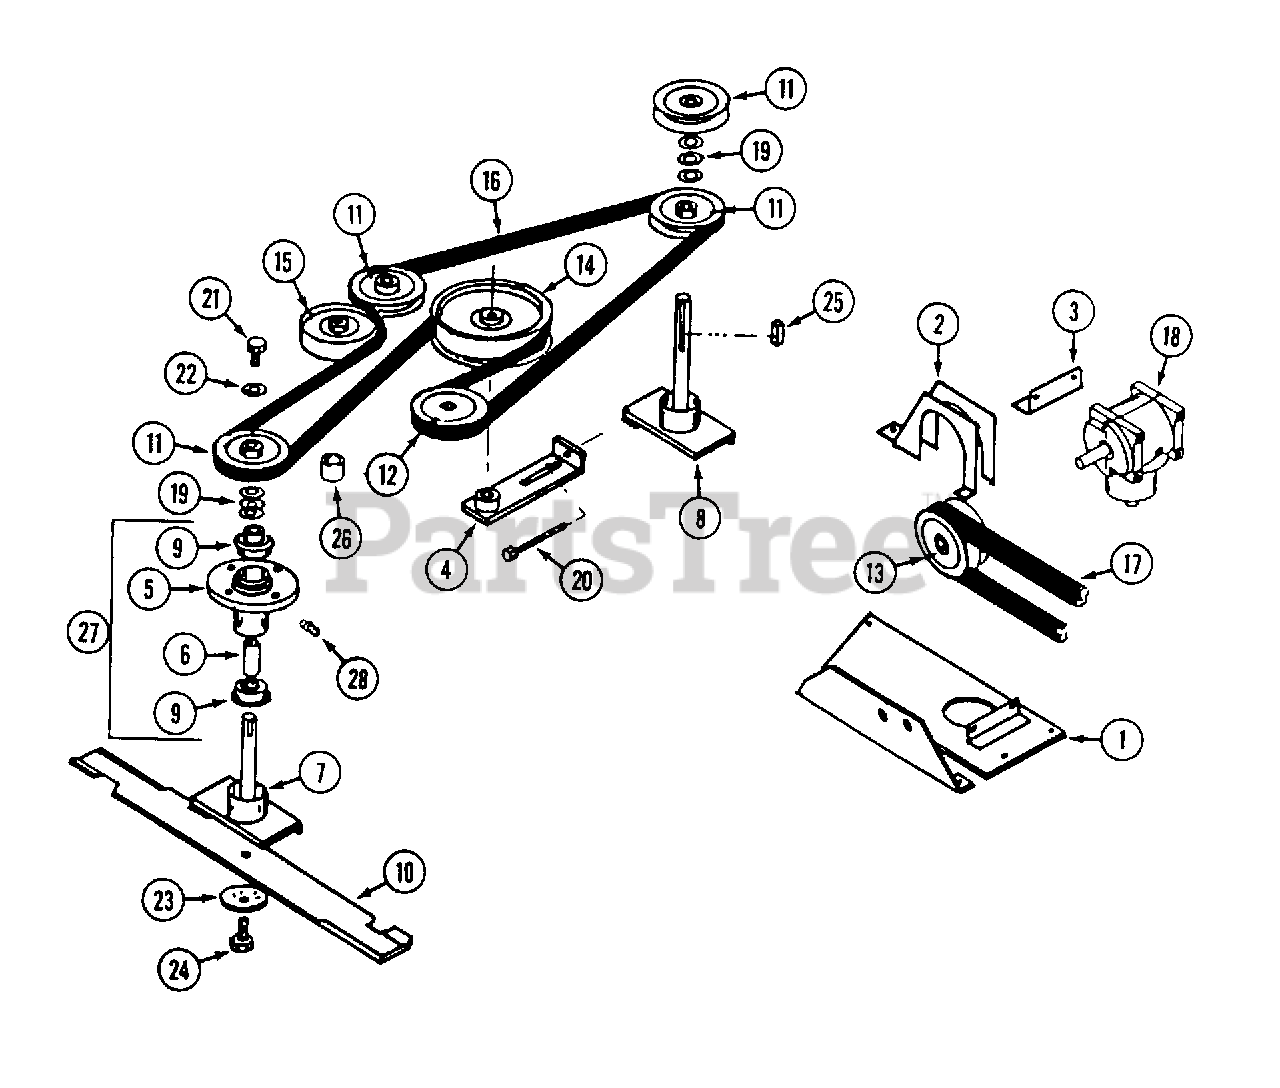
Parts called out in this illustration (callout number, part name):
1	MOUNT - gear box
3	ANGLE - gear box mount
4	TIGHTENER - belt
5	HOUSING - spindle
6	SPACER spindle
7	SHAFT - spindle, short
8	SHAFT - spindle, long
9	BEARING - spindle
10	BLADE
11	PULLEY - spindle
12	PULLEY - gear box output
13	PULLEY - gear box input
14	PULLEY - idler, large
15	PULLEY - idler, small
18	GEAR BOX - angle drive
19	WASHER - spacer
20	BOLT - 1/4" - 20 x 4"
21	BOLT - 5/16" - 24 x 3/4"
22	WASHER - 5/16", 10 ga
23	WASHER - blade
24	BOLT - 3/8" - 24 x 1-1/4"
25	KEY - 3/16" x 3/16" x 1"
26	SPACER - idler pulley
27	HOUSING ASSEMBLY - spindle
28	FITTING - grease 1/4" - 28
